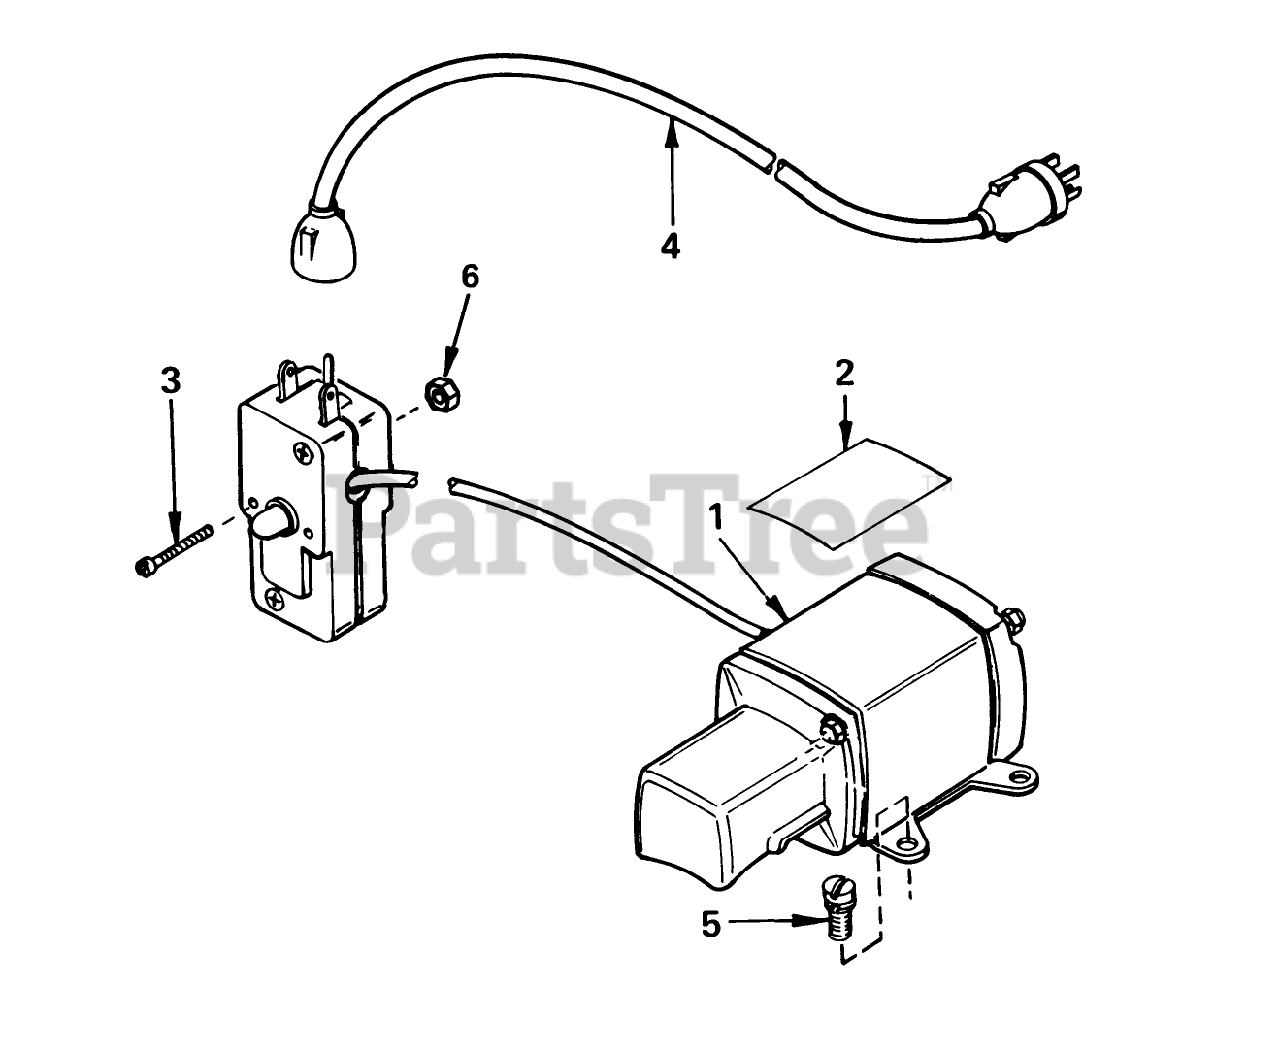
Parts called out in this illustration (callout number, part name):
1	Motor, Cranking (CSA Approved)(Incl. #2 thru 6)
2	Decal
3	Screw, Pan Hd.
4	Cord-Extension
5	Screw (T-30, 1/4-20 x 23/32)
6	Nut & Lockwasher
